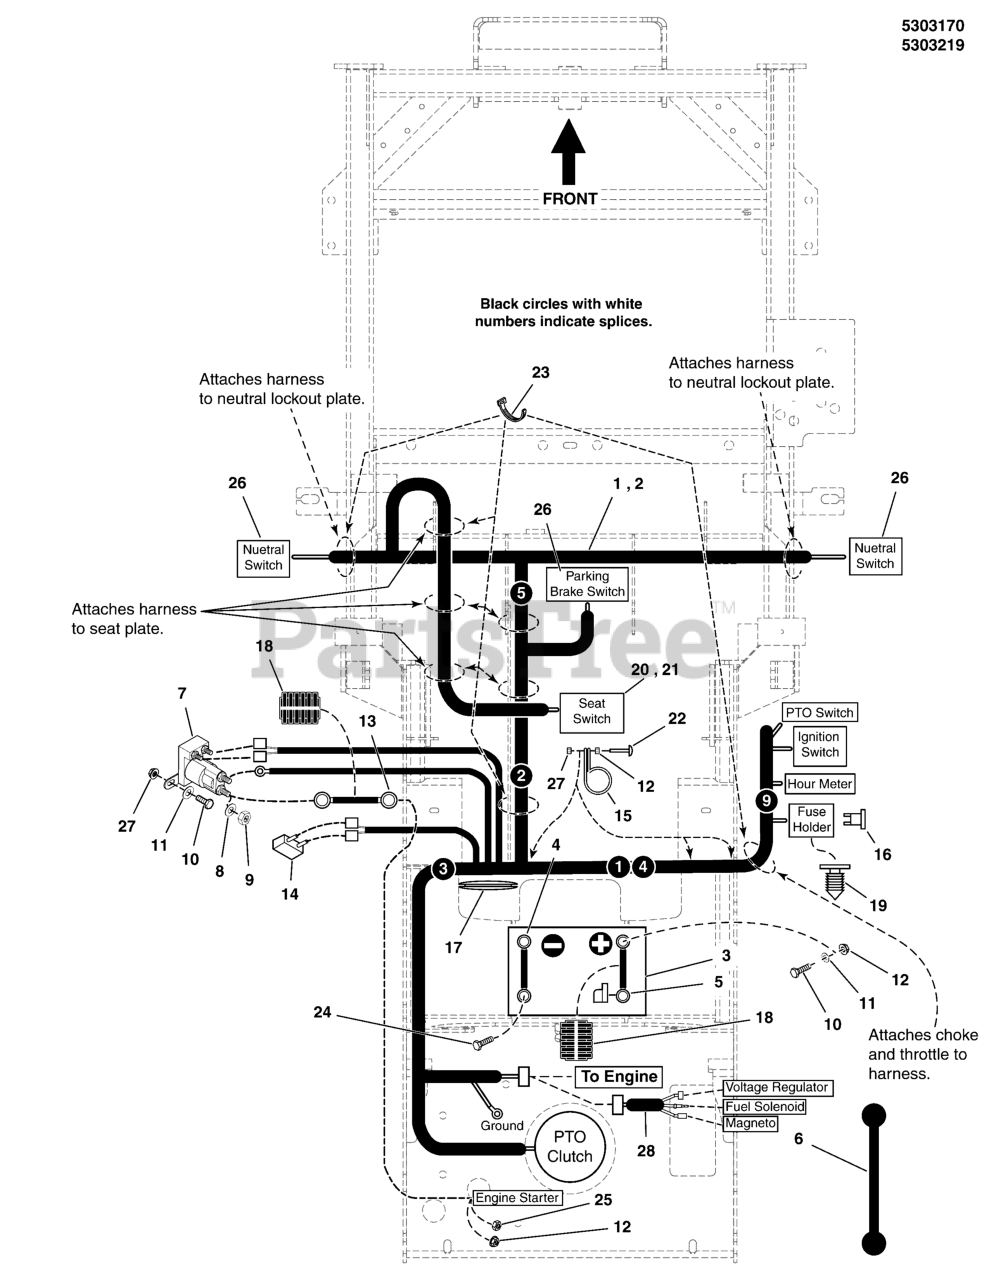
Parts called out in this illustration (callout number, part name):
1	WIRE HARNESS, C TURF,WARNER, S125XT
3	BATTERY, WET ( BCIU1, 340 CCA)
4	BATTERY CABLE, NEGATIVE, 14"
5	BATTERY CABLE, POSITIVE, 22
6	STRAP-BLACK RUBB
7	SOLENOID-4 POLE 12 VOLT DC (TROMBETTA)
8	WASHER, 5/16 LIGHT LOCK
9	NUT, 5/16-24 JAM
10	BOLT, 1/4-20 X 3/4 GD5 YZ
11	WASHER, 1/4 SAE
12	NUT, 1/4-20 HEX SERR. FLANGE
13	BATTERY CABLE, POSITIVE, 22
14	BREAKER-CIRCUIT 12VOLT 20AMPS W/TAB
15	CLAMP, VINYL INSULATED
16	FUSE, ATO 15 AMP
17	GROMMET, 1-1/2" ID FOR 1/4" METAL
18	WIRE LOOM, 3/8 ID X 18 IN
19	FIR TREE MOUNT, PACKARD
20	SWITCH, NC, W/ BOLT-IN BASE
21	SWITCH, NC, W/ TWIST-IN BASE
23	TIE, SELF-LOCKING, 12"
24	BOLT, M8-1.25 X 2.MM GD 8.8
25	NUT, HEX, M8-1.25, CZ, GD 8.8
26	SWITCH, DP NO/NC SNAP-IN
27	NUT, 1/4-20 HEX NYLOCK FLANGE
28	WIRE HARNESS, JUMPER, KAWI
